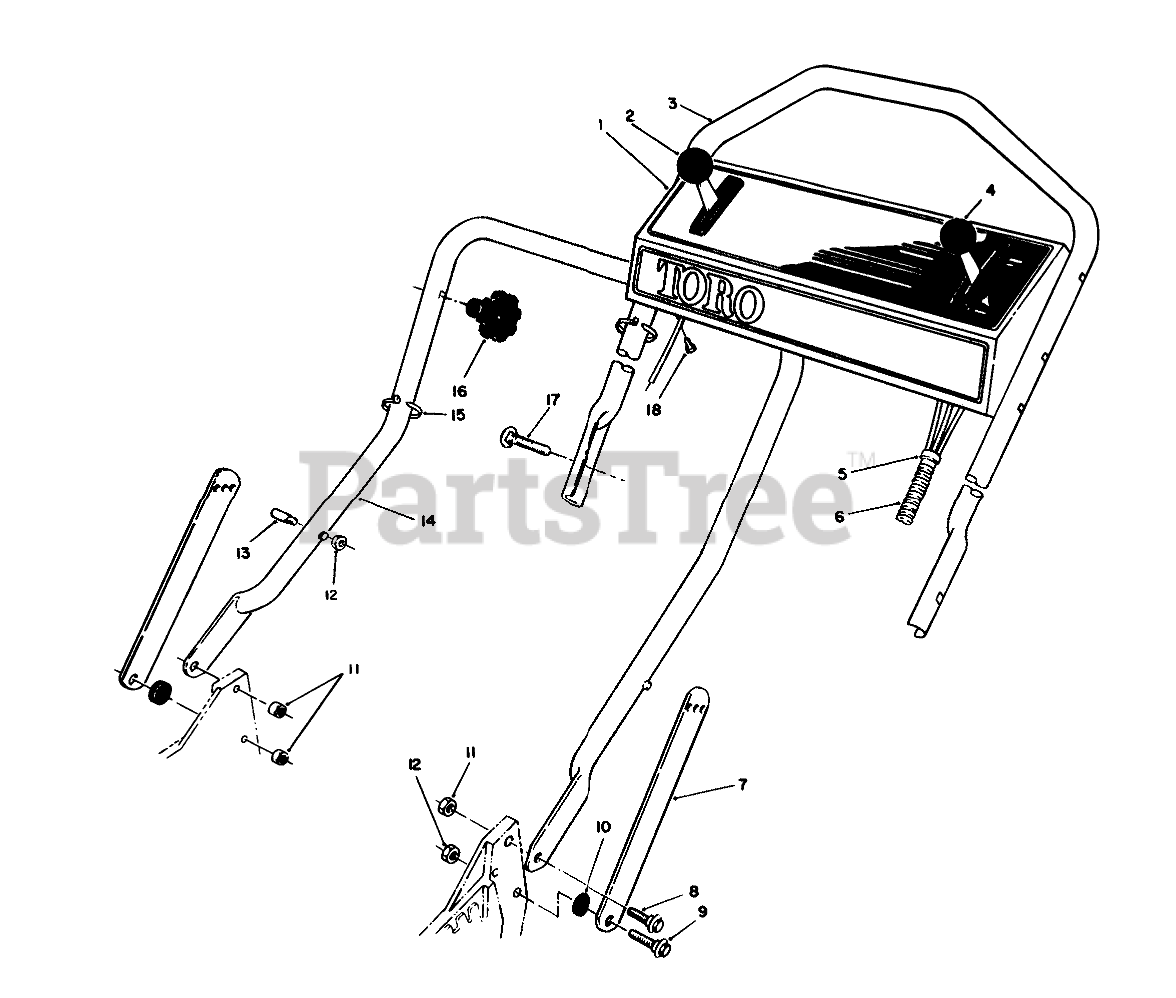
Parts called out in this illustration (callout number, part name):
1	Panel-Control
2	GROUND SPEED CONTROL
3	Handle-Upper
4	Control-Throttle (Bend #5)(Sheath Lg. 55-7/8 inches)(Wire Lg. 2-3/8 inches)
5	CONTROL CABLE COVER
6	FITTING-RING
7	Handle Latch
8	SCREW-SHOULDER
9	SCREW-SHOULDER
10	SPACER
11	NUT-LOCK, NI
12	NUT-LOCK, NI
13	HANDLE PIN
14	LOWER HANDLE ASM
15	TIE-CABLE
17	5/16-18 X 2 HNDLE SCREW
18	SCREW-HWHTF
